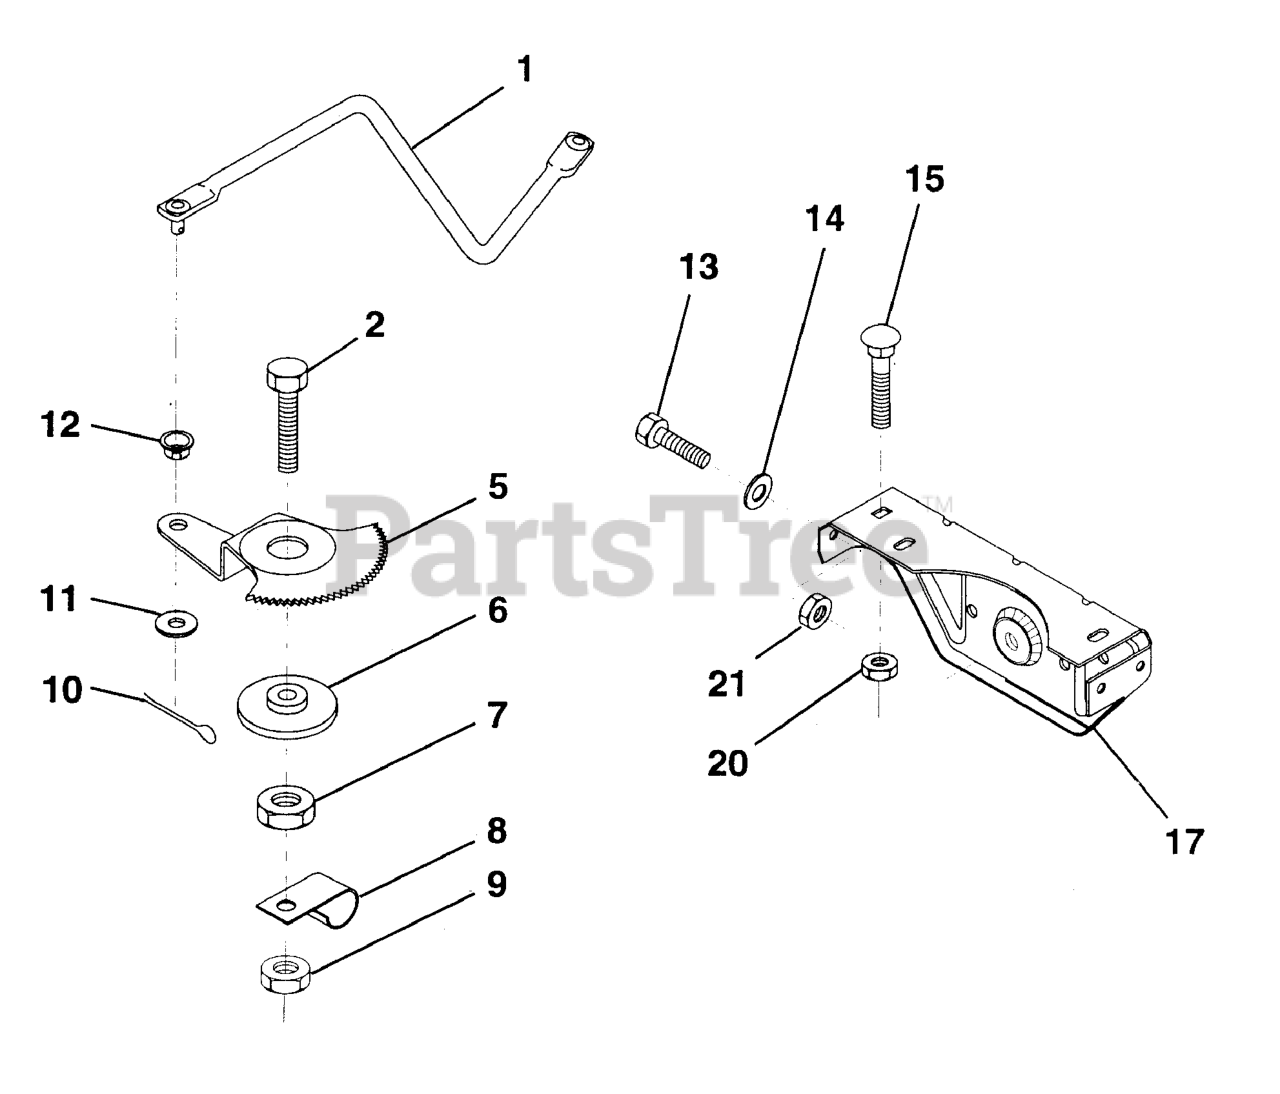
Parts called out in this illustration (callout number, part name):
5	GEAR SECTOR
7	NUT
8	CLIP INSULATOR
9	NUT LTV
10	COTTER PIN
11	WASHER
12	BUSHING.DRAGLINK (2 2)
13	BOLT
14	WASHER
15	BOLT
17	SUPPORT/AXLE FRONT
20	NUT
21	NUT.71038.31-18.HEX.NYLOCK
